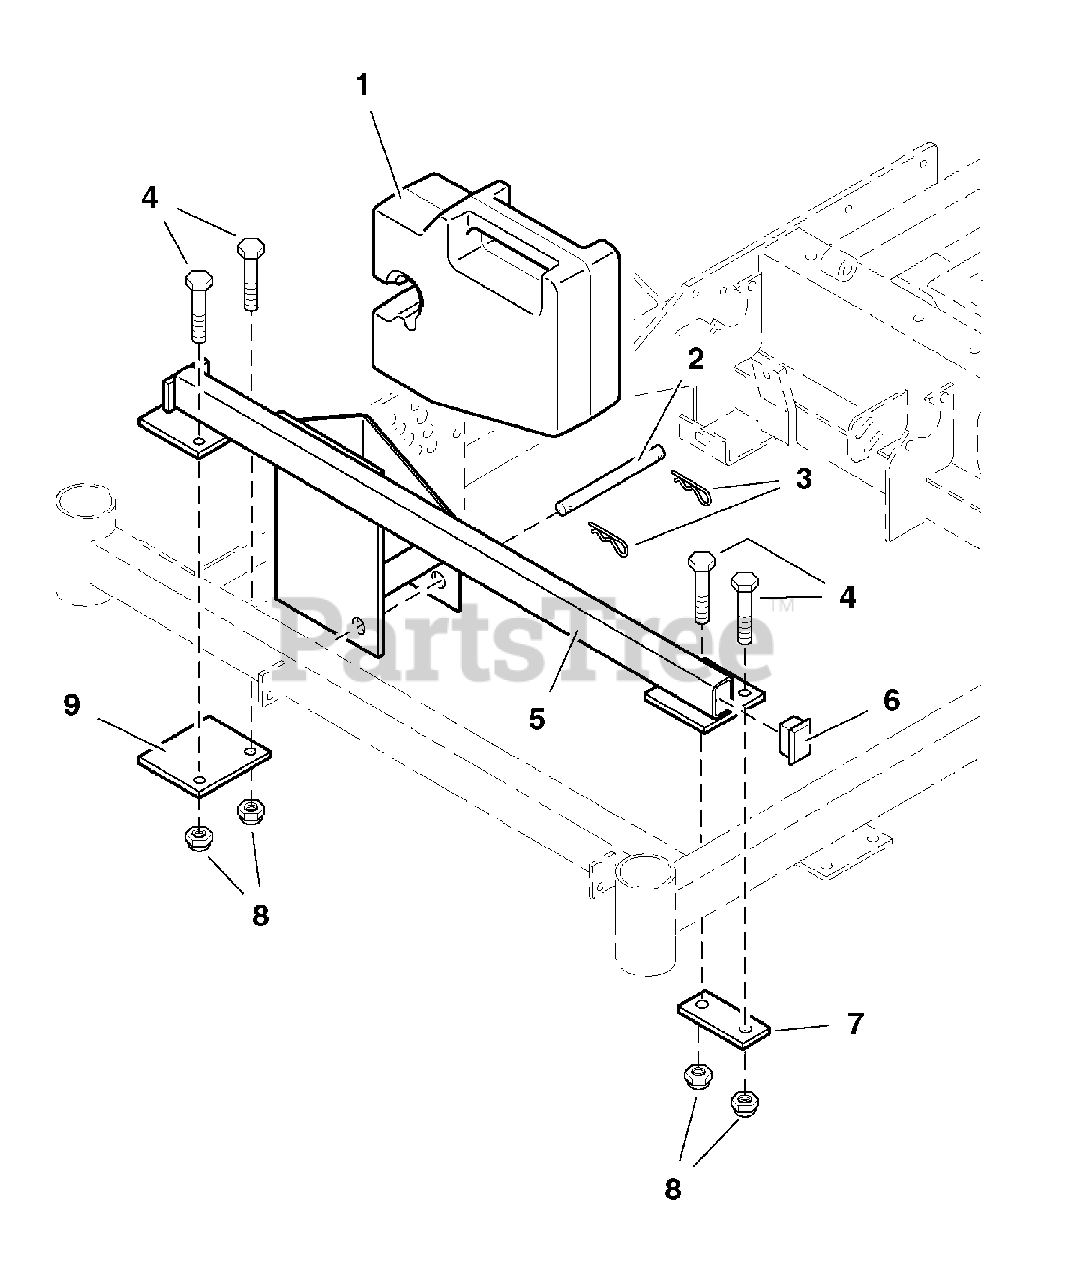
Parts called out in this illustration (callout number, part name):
1	COUNTERWEIGHT, 50lbs
2	RETAINING PIN
3	HAIR PIN CLIP
4	CAPSCREW, Hex Hd, 3/8-16 x 3
5	WEIGHT MOUNT FRAME
6	CAP, Plastic
7	BRACE PLATE, Lower
8	NUT, Hex, Nylon Lock, 3/8-16
9	MOUNT PLATE, Lower
